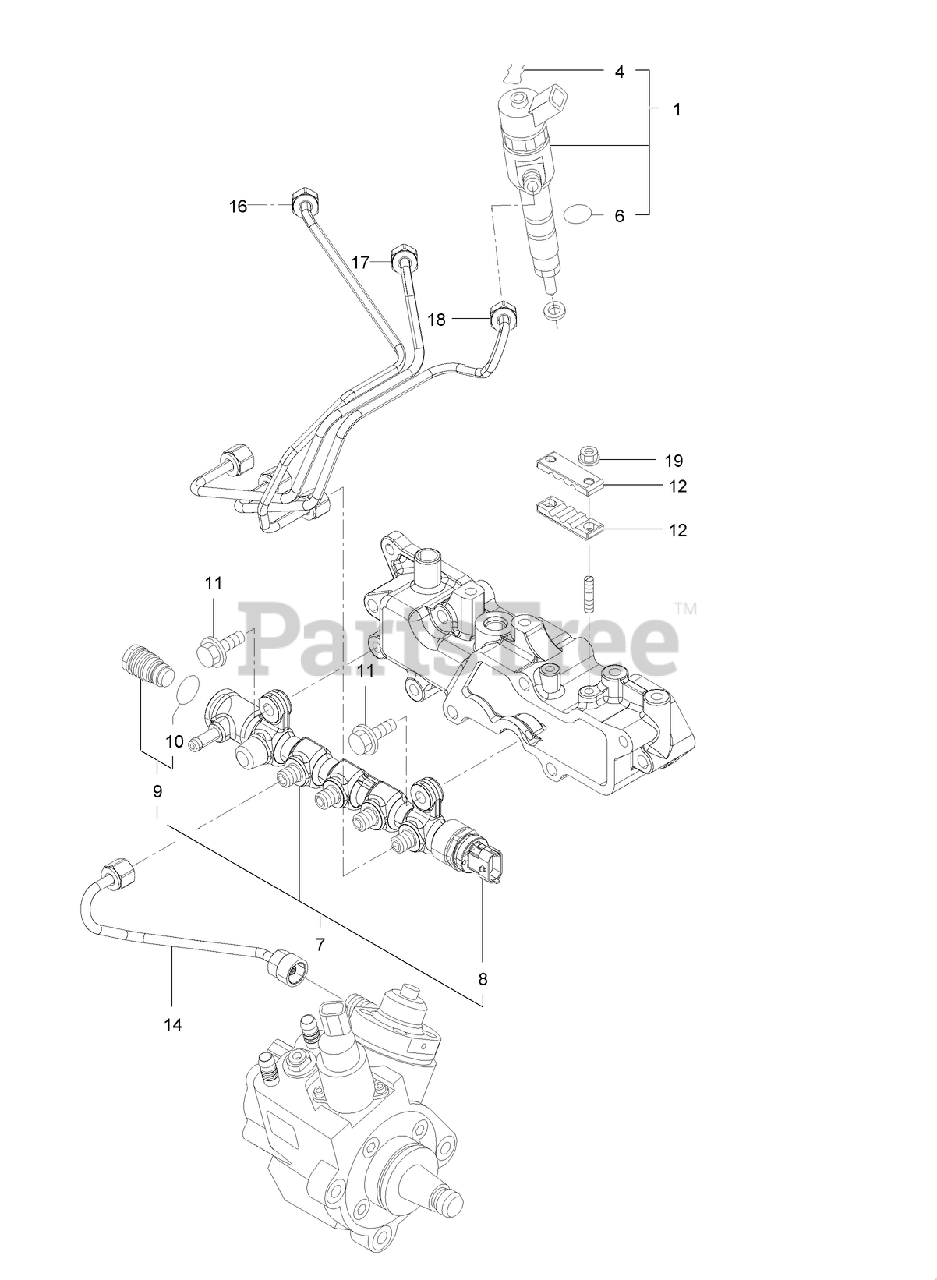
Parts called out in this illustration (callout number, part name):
1	INJECTOR ASM
4	RING-RETAINING
6	O-RING
7	RAIL ASM
8	SENSOR-PRESSURE, RAIL
9	VALVE ASM
10	O-RING
12	RETAINER
14	RAIL IN PIPE ASM
16	INJECTION PIPE ASM
17	INJECTION PIPE ASM
18	INJECTION PIPE ASM
